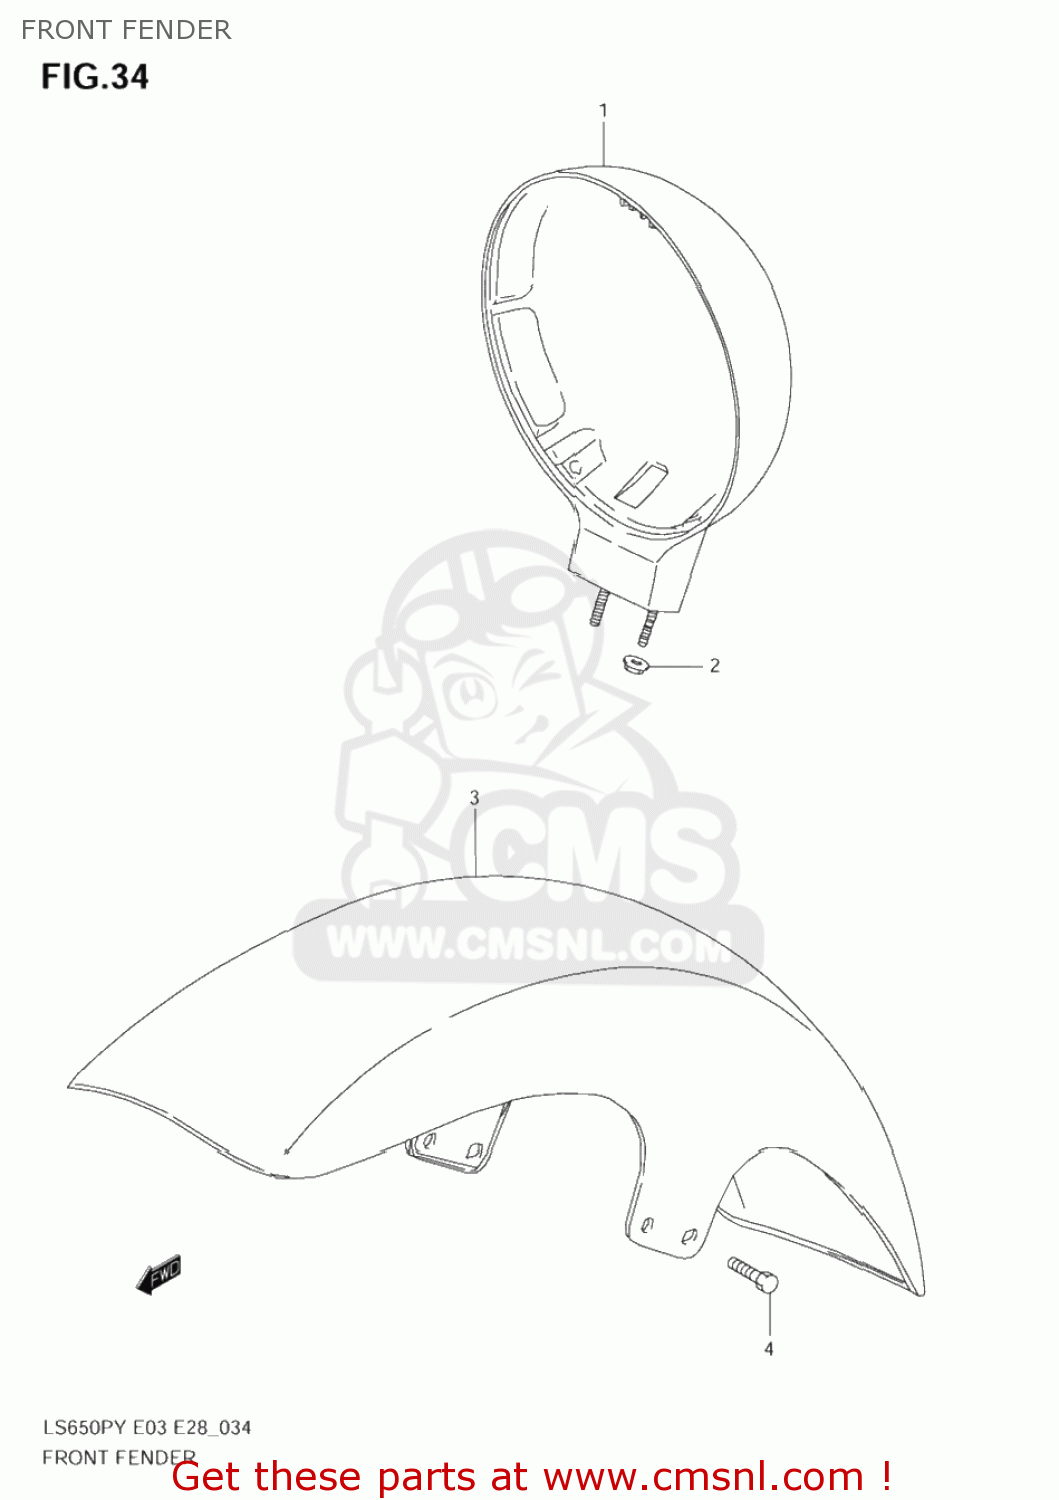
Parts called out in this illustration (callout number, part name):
1	HOUSING,HEADLAMP
2	NUT
3	FENDER,FR
4	BOLT
